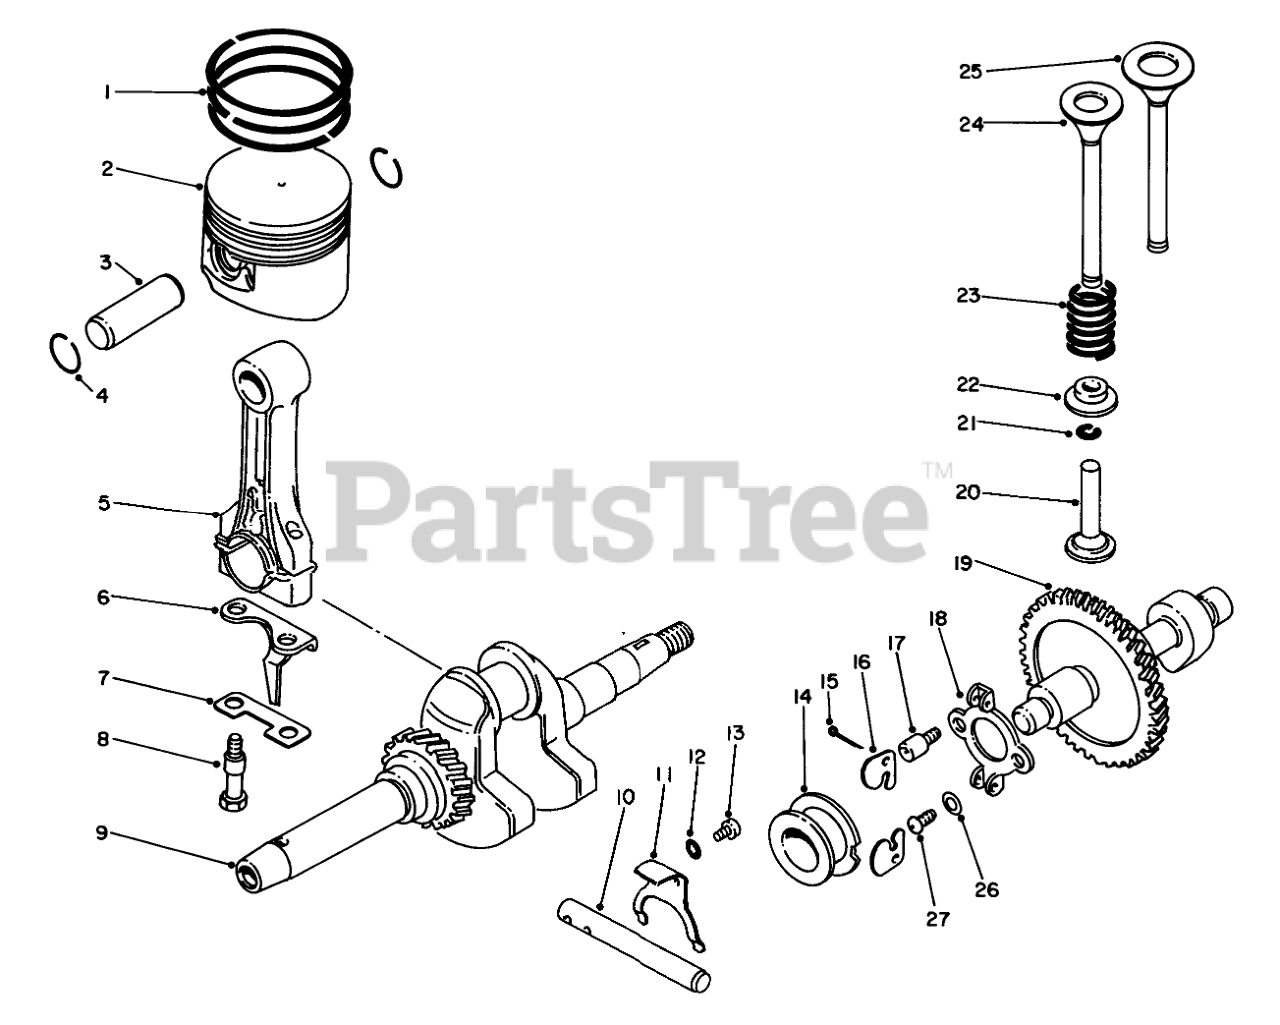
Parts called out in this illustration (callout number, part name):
1	Ring Set-Piston Std.
2	Piston Std.
3	Pin Piston
4	CIRCLIP
5	Rod-Connecting (Incl. Ref. #6-8)
6	Plate-Splasher
7	LOCK PLATE
9	Crankshaft
10	SHAFT-THROTTLE TURN
11	SHIFT PLATE
12	Washer
13	SCREW
14	Spacer
15	Cotter Pin
18	BRACKET
19	Cam Shaft
20	TAPPET
21	Cotter-Valve
22	Retainer-Spring
23	Spring-Valve
24	VALVE, EXHAUST
25	VALVE, INTAKE
26	Washer
